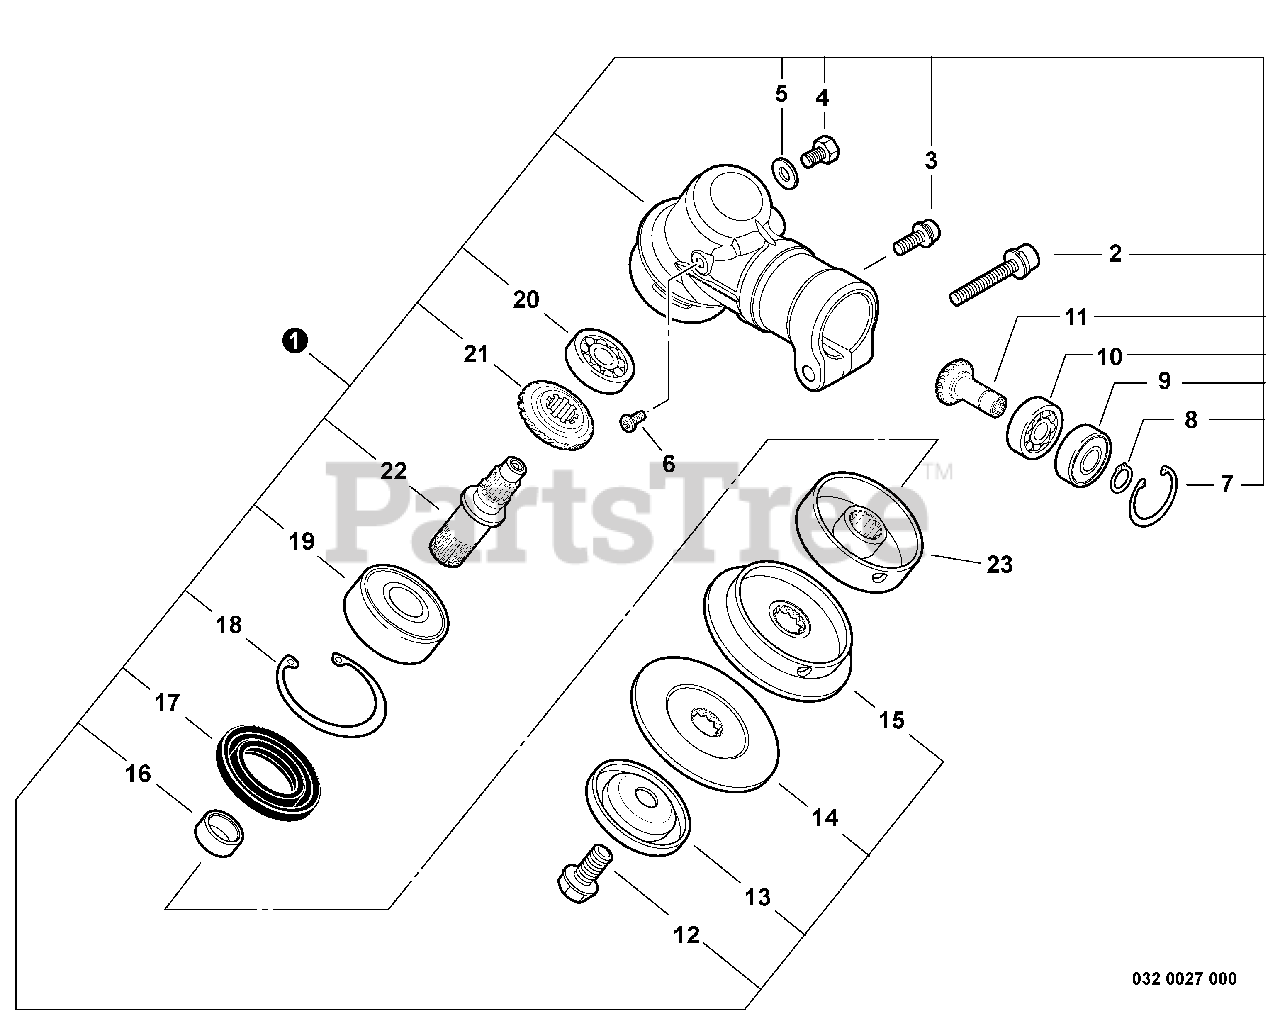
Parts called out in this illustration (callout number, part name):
1	GEAR CASE ASSY
2	SCREW - 6X40
3	SCREW - 5X10
4	BOLT - 6X10
5	WASHER - 6
6	SCREW - 4X6
7	RING, RETAINING - 26
8	RING, RETAINING - 10
9	BEARING, BALL - 6000ZZ
10	BEARING, BALL - 6000
11	GEAR - PINION
12	BOLT - 8X22
14	ADAPTOR, BLADE - LOWER
15	ADAPTOR, BLADE - UPPER
17	SEAL, OIL
18	RING, RETAINING - 32
19	BEARING, BALL - 6201
20	BEARING, BALL - 609
21	GEAR - SPUR
22	GEAR - SHAFT
23	ADAPTOR, BLADE - UPPER
